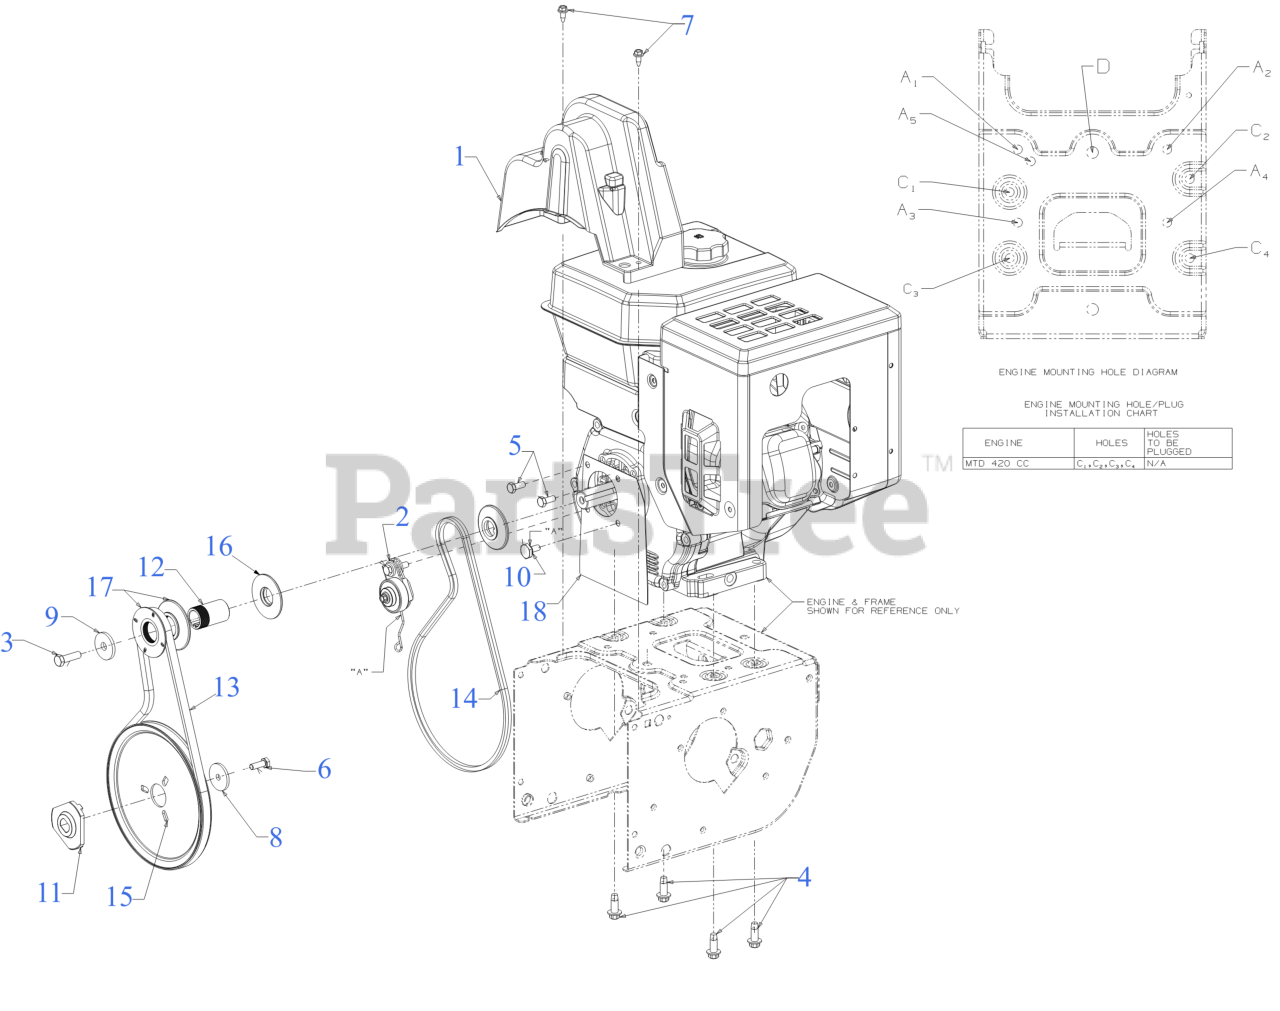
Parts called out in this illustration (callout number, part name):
1	BELT COVER SERVICE KIT (631-05323)
2	IDLER ASSEMBLY
3	SCREW 3/8-24X1.25
4	SCREW 3/8-16 x 1
5	SCREW 5/16-24 x .750 GR5
6	SCREW 5/16-24 x .875 GR5
7	SCREW 1/4-20X.625
8	FLAT WASHER
9	FLAT WASHER .45 x 1.5 x .172 HT
10	SHOULDER SCREW
11	ADAPTER PULLEY .75 DIA W/DD
12	PULLEY SPACER
13	BELT-.500 x 37.00
13	Cub Cadet AUGER BELT
13	Troy-Bilt AUGER BELT (04195)
14	BELT-3L x 36.64 LG
14	Troy-Bilt 23" BLADE (BOWTIE)
15	AUGER PULLEY
16	HALF PULLEY 3/8-V x 2.2
17	HALF PULLEY A2.76 x 1.140 SPLINE
18	ENGINE PLATE (FRONT COVER)
